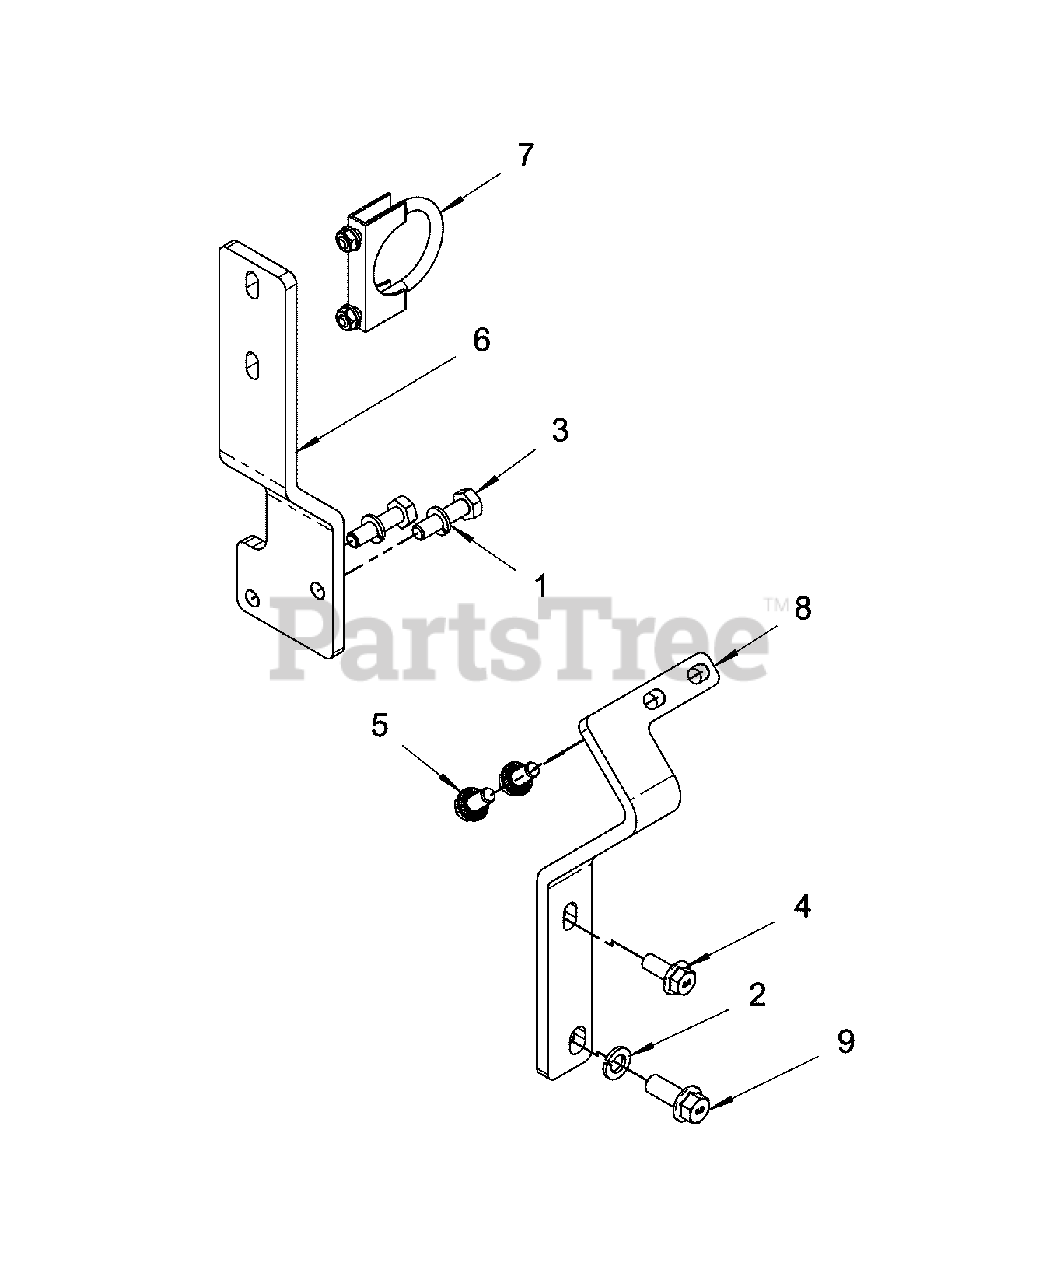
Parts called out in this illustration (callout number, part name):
1	* WASHER
2	* WASHER
3	* BOLT
4	* BOLT
5	* BOLT
6	* SUPPORT BRACKET
7	* U-BOLT
8	* MIXER SUPPORT BRACKET
9	* BOLT
